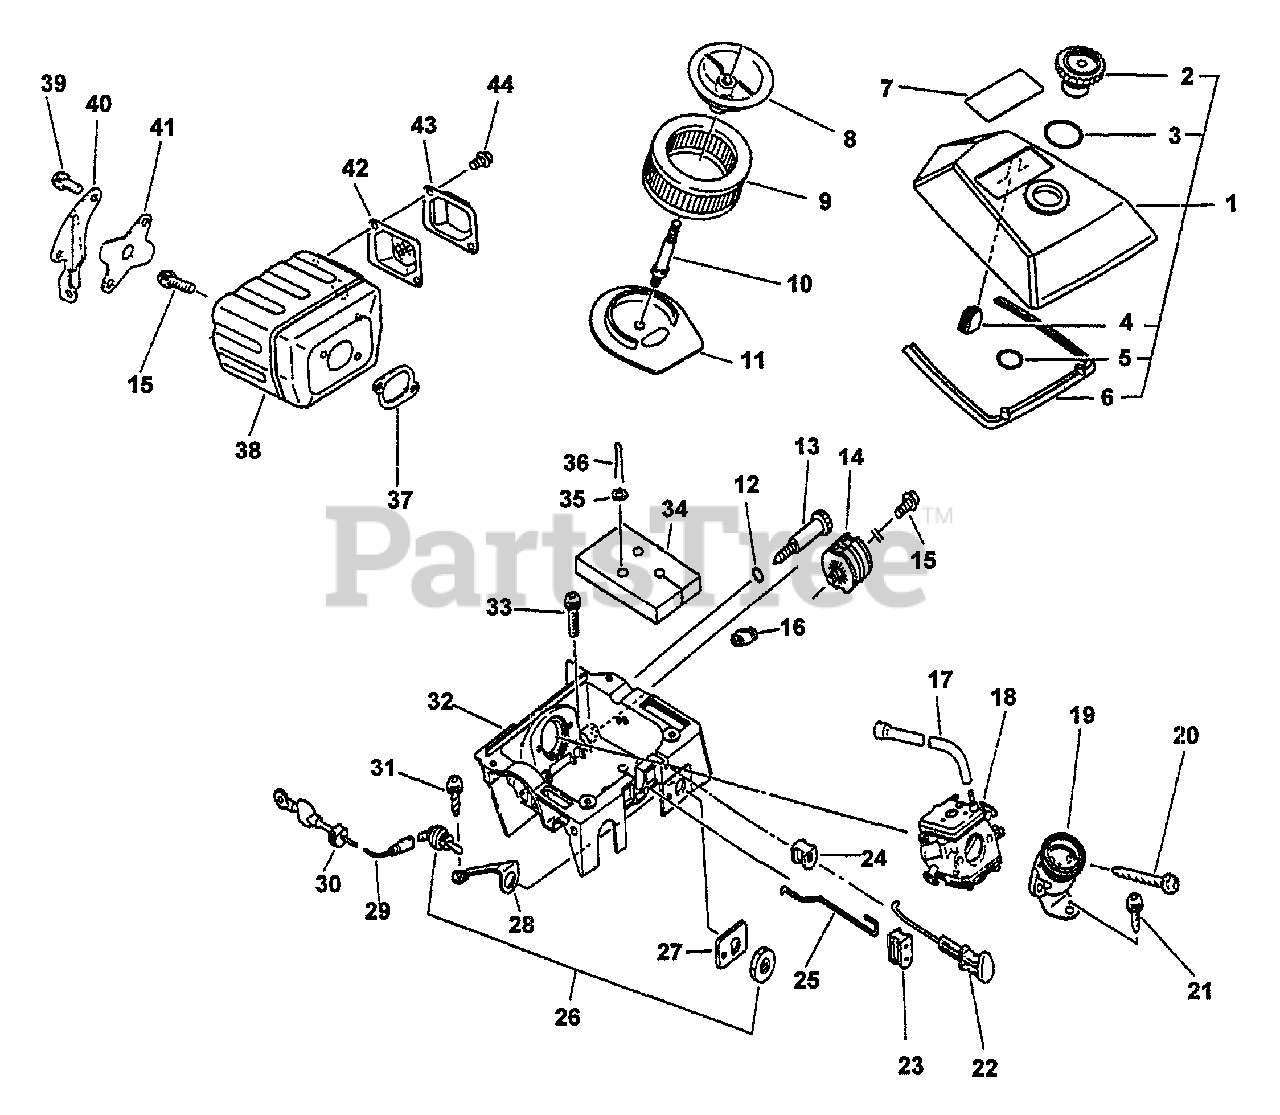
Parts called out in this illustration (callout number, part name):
1	AIR FILTER COVER ASSY
2	THUMBSCREW
3	O-RING -21
5	O-RING P-11
6	GASKET, AIR FILTER
7	LABEL, CS-6700
8	BRACKET, AIR FILTER
9	FILTER ASSY, AIR
10	STUD
11	BRACKET, AIR FILTER
12	O-RING 7 MM
13	SCREW, IDLE ADJUST - GRAY
15	BOLT 5×20
17	PIPE, IMPULSE
18	CARBURETOR
19	ADAPTOR, INTAKE
20	SCREW 5×53
21	SCREW 5×14
22	ROD, CHOKE
23	GROMMET, THROTTLE ROD
24	GROMMET
25	ROD, THROTTLE
26	SWITCH, ON-OFF
27	LABEL, STOP
28	PLATE, GROUND
29	LEAD
31	SCREW 5×10
32	CASE, CARBURETOR
33	BOLT 5×14
34	GASKET, CARBURETOR CASE
36	PIN, COTTER 3×18
37	GASKET, EXHAUST
38	MUFFLER
39	SCREW 5×14
40	BRACKET, MUFFLER
41	COVER, MUFFLER
42	SCREEN, SPARK ARRESTER
43	OUTLET, EXHAUST
44	BOLT 4×10
